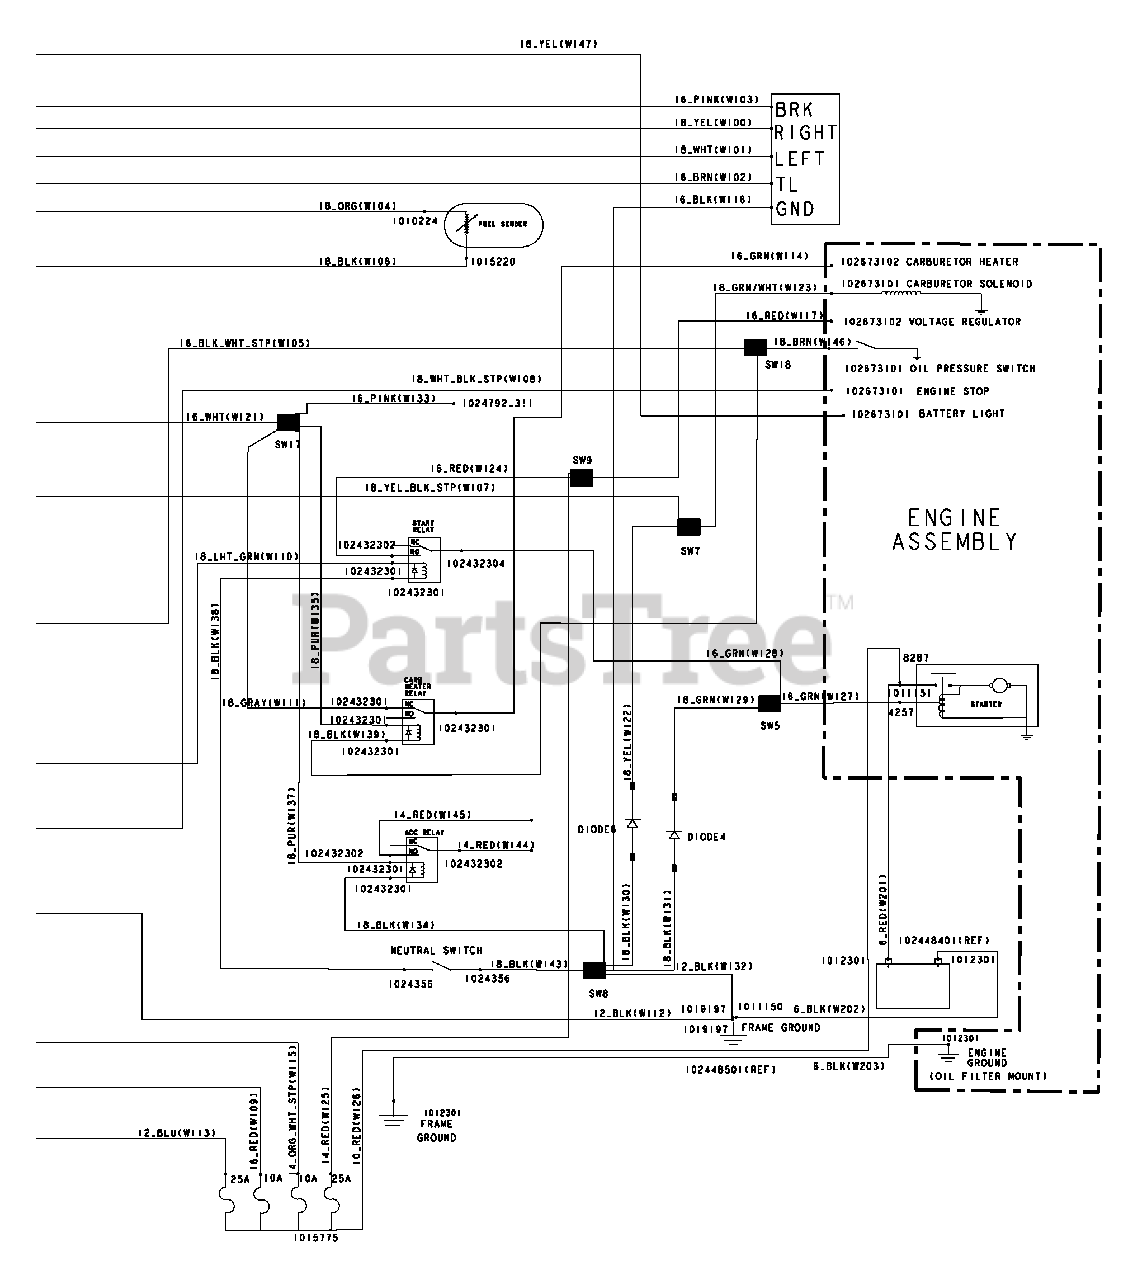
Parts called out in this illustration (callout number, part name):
1	Diode, General Purpose, 6.0a
2	Harness, AWD, Kawasaki
3	Asm, Switch, Limit, Awd
